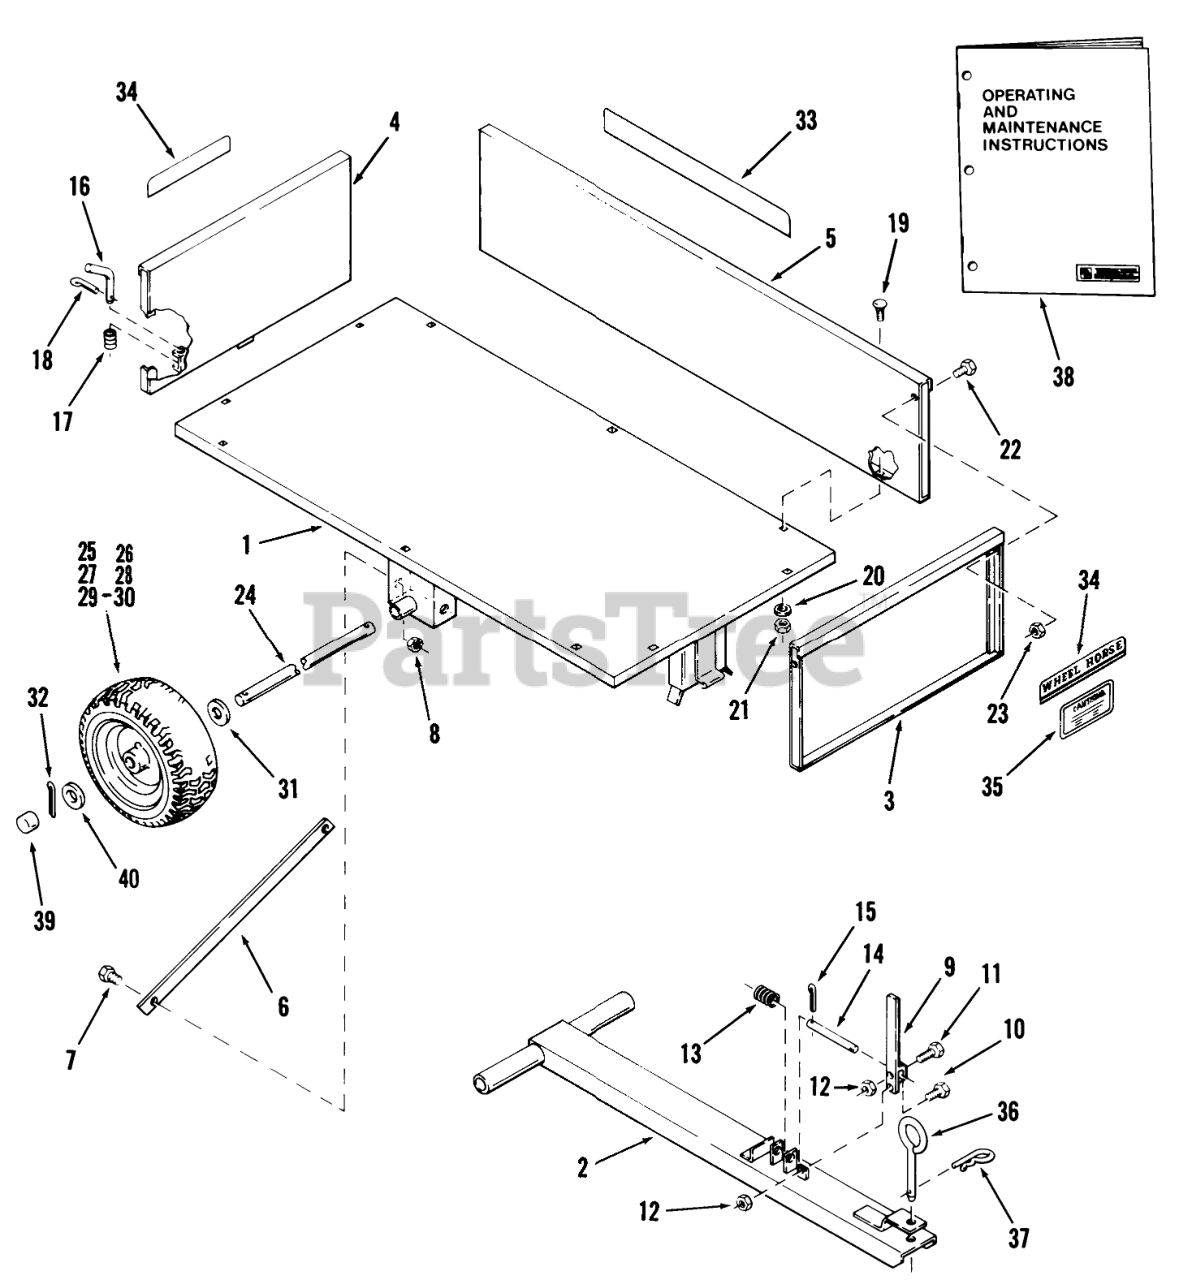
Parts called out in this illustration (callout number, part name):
2	Drawbar
3	Front Panel
4	Rear Gate
5	Side Panel
6	Cross Brace
7	Bolt
8	Nut
9	Latch Handle
10	Bolt
11	Bolt
12	Nut
13	SPRING-COMPRESSION
14	Index Pin
16	Latch Handle, Gate
17	SPRING-COMPRESSION
18	Cotter Pin
19	Carriage Bolt
20	Washer
21	Nut
22	Bolt
23	Nut
25	ASSY-WHEEL&TIRE
26	Wheel
27	TIRE TURF SAVER 16X6.50-8
28	VALVE
29	Wheel Bearing
30	TUBE-INNER
31	WASHER
32	Cotter Pin 3/16 X 1 1/2
33	DECAL
34	DECAL-REAR
35	Weight Limit Decal
36	PIN-TOOL
37	Hairpin Cotter
38	Operating and Maintenance Instructions
39	HUB CAP
